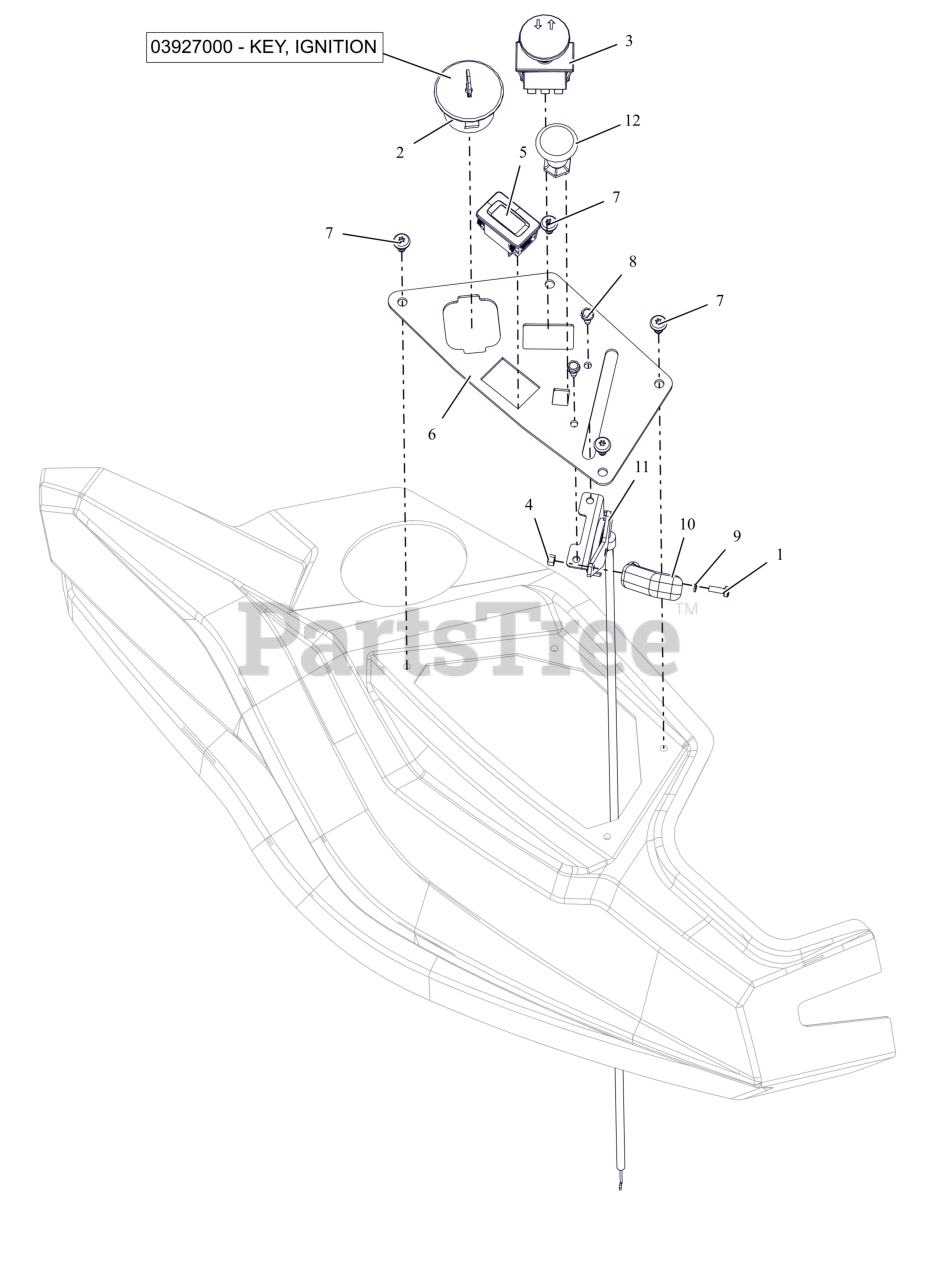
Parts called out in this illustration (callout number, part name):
1	M4 X 12 POZI PAN MACHINE SCREW
2	KEYSWITCH-IGNITION 3 POS
2	KEY, 03290500 KEYSWITCH
3	SWITCH, CLUTCH (YELLOW)
4	NUT, NYLOC M4
5	HOUR METER
6	PANEL- CONTROL
7	SCR-PAN .25-15X.50 6L H/LZB500
8	SCR,TAP #10-24X.50 HWH TR ZCC
9	CAP,TANK
10	KNOB, CONTROL
11	THROTTLE, LONCIN LC2P76F 635CC
12	CABLE, CHOKE
